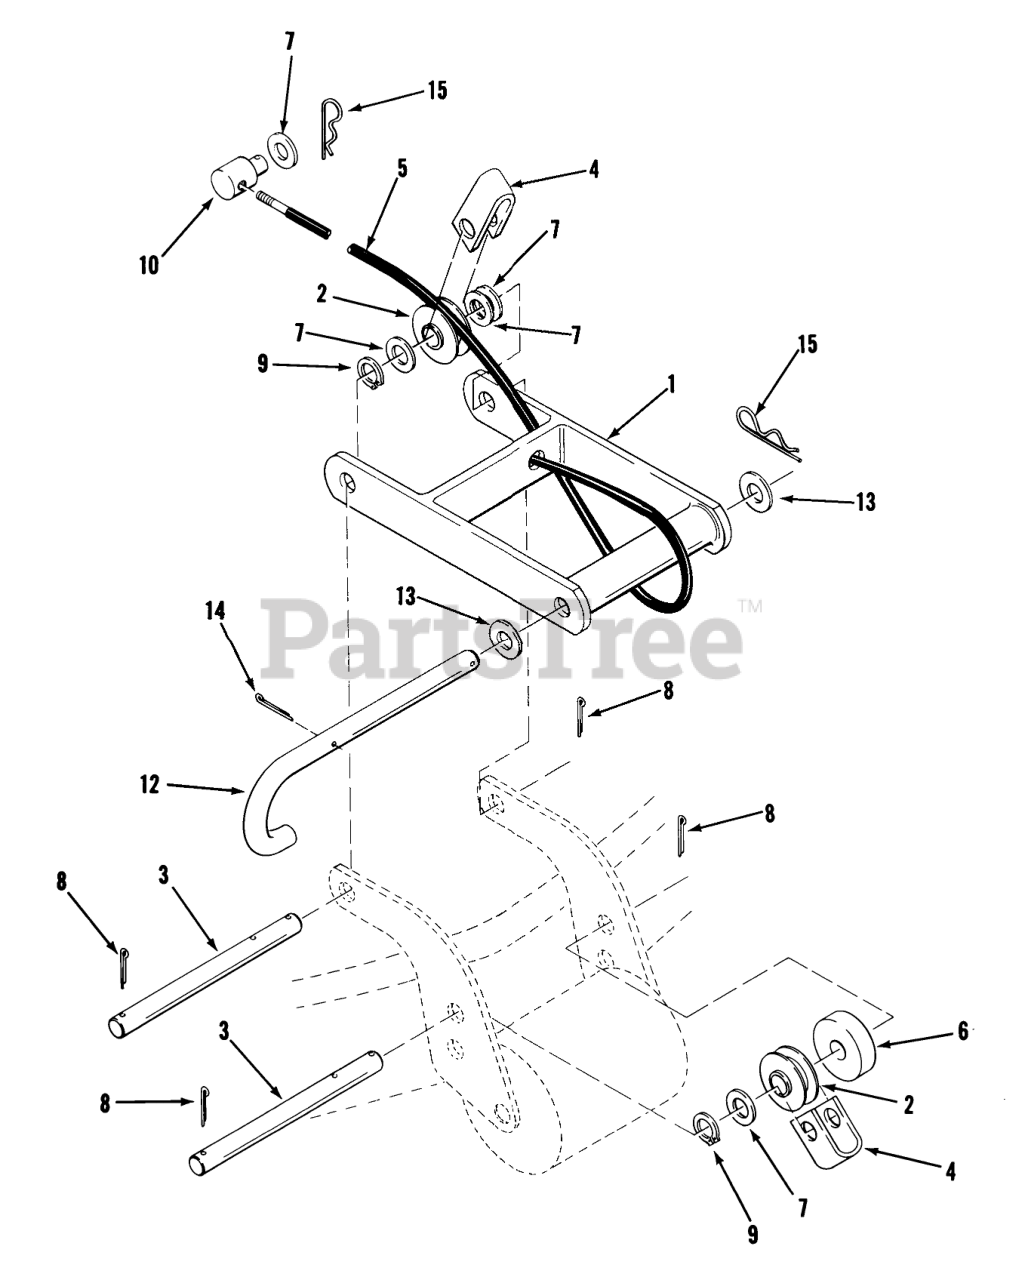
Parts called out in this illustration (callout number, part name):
1	ASSY-FRNT HSG MOUNT
4	STRAP-CABLE
6	SPACER
9	GRIP RING
10	TRUNNION-CLUTCH ROD
15	Hairpin Cotter
